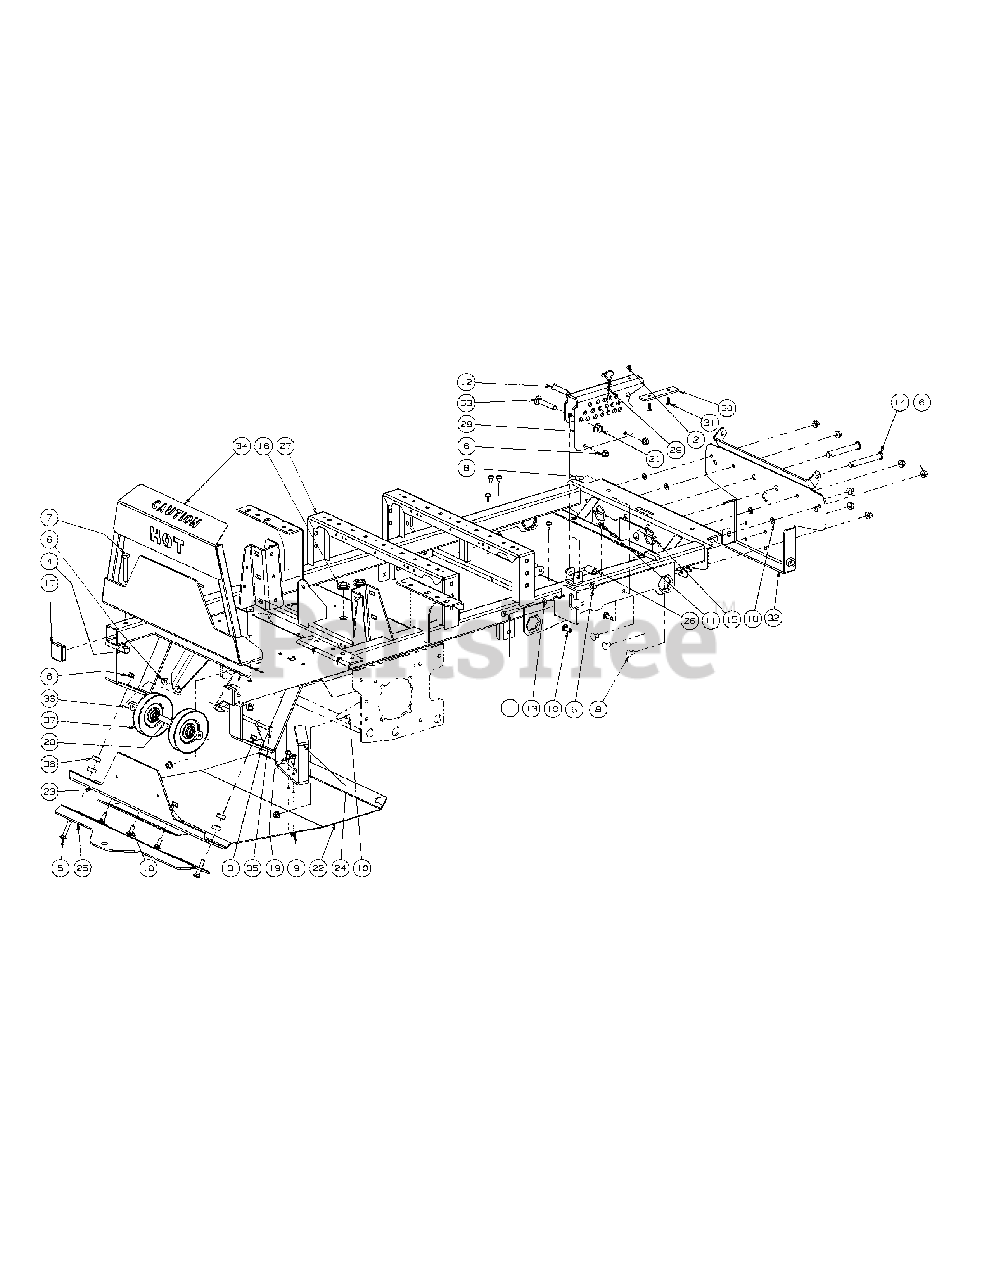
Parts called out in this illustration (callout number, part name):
1	Hex Cap Screw 3/8-16 x 2.00
2	Lock Nut w/Nylon Insert
3	Flat Washer, 3/8
4	Lock Nut, Nylon Insert, 1/2-13
5	Carriage Bolt, 3/8-16 x 2.00
6	Hex Nut, 3/8-16 Flange Lock
7	Hex Head Cap Screw, 1/2-13 x 3.00
8	Carriage Bolt, 3/8-16 x .75 Long
9	Nut, 5/16-18, Hex Flange Lock
10	Carriage Bolt, 3/8-16 x 1.0
11	Rubber Bumper, .62 OD x .22 Thick
12	Clevis Pin, .500 Dia. x 2.50 Lg.
13	Nut, 3/8-16, Jam
14	Clevis Pin, .625 Dia x 4.375 Long
15	Linch Pin, 3/16 Dia.
16	Grommet, .75 ID
17	Plug, Square Tube
18	Push Retainer, 3/8
19	Self Tapping Screw 5/16-18 x .750
20	Spacer, .385 ID x .625 OD x 4.89
21	Nut, 1/2-13, Flangelock
23	Guard Bracket
26	Spacer, .51 ID x .75 OD x 1.40
27	Frame Assembly
28	Lift Index Bracket
29	HitchPin, .120 Dia. x 3.0
30	Wear Plate, 1.125 x 5.00
31	Flat Head Cap Screw, 1/4-20 x .75
32	Bracket Assembly, Frame, Front
33	Carriage Bolt, 1/2-13 x 3.00
34	Muffler Guard Assembly
35	Hex Head Cap Screw, 3/8-16 x 8.50
36	Spacer, .406 ID x 1.00 OD x .380
37	Idler Pulley, 5.06 Dia.
